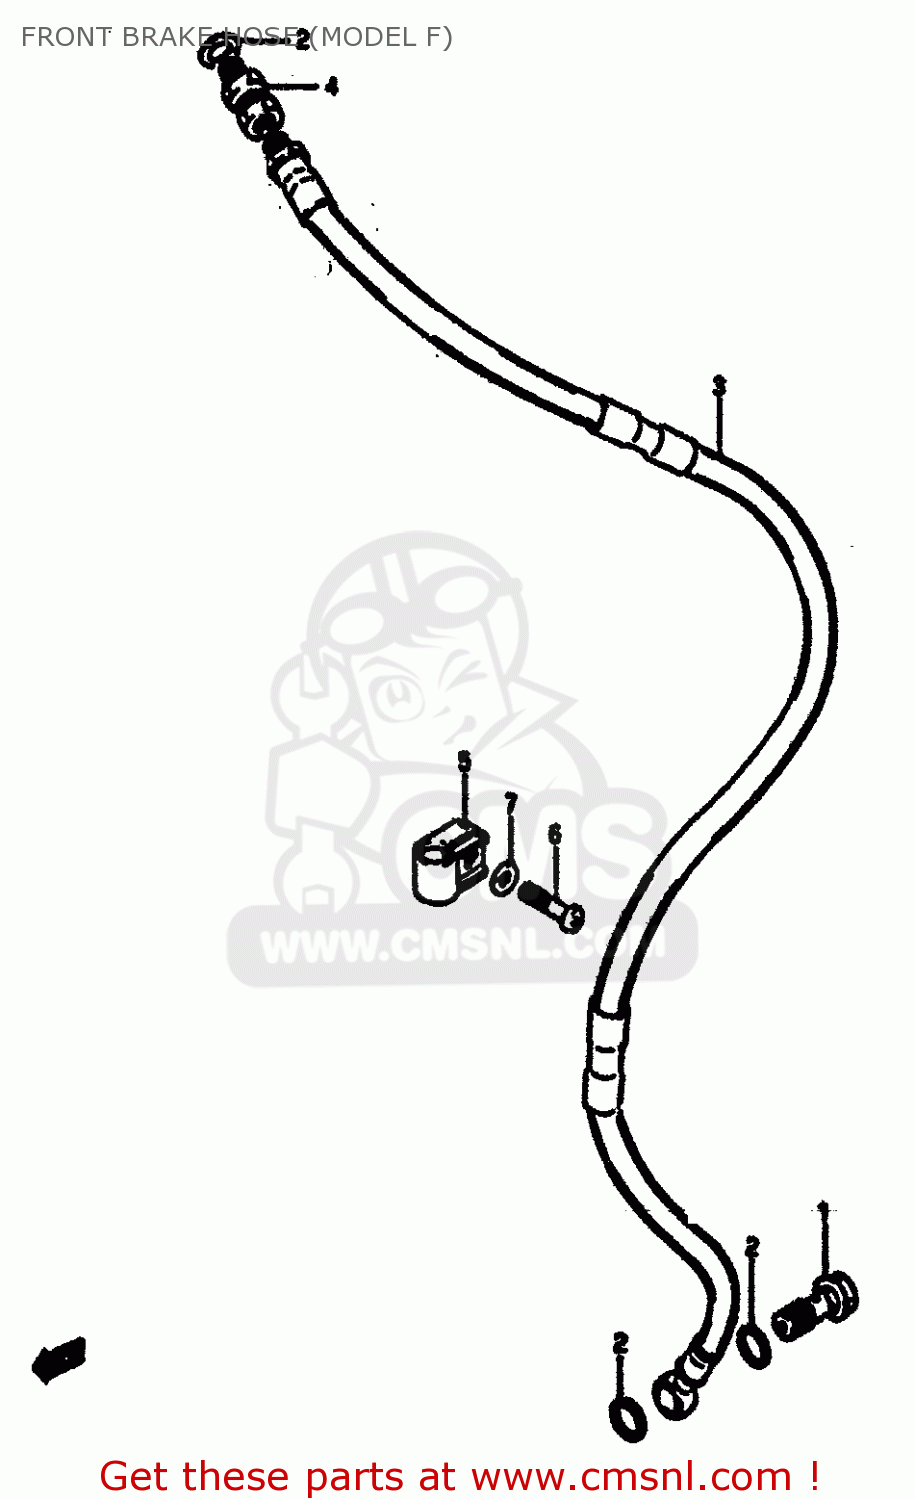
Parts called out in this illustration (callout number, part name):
1	BOLT UNION
2	WASHER(10X15X1.5)
3	HOSE,FRONT BRAKE
4	ADAPTER,BRAKE HOSE
5	CLAMP,FRONT BRAKE HOSE
6	SCREW
7	WASHER
